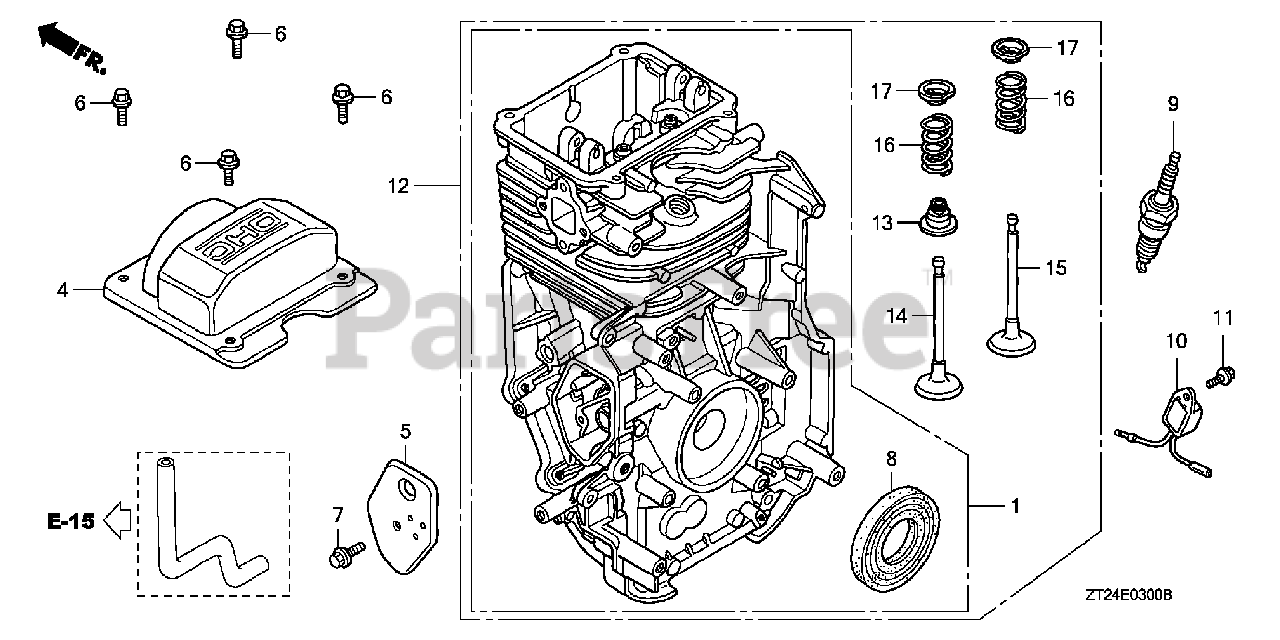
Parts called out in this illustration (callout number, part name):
4	COVER, CYLINDER HEAD
4	COVER, HEAD
5	COVER, BREATHER (BREATHER VALVE ASSY.)
6	BOLT, FLANGE (6X12) (CT200)
7	BOLT, FLANGE (6X14) (CT200)
8	OIL SEAL (25.4X62X6)
9	SPARK PLUG (BPR6ES) (NGK)
10	ALERT UNIT, OIL
11	BOLT, FLANGE (6X12) (CT200)
12	CYLINDER ASSY.
13	SEAL, VALVE STEM
14	VALVE, IN. (ROCKNEL)
15	VALVE, EX.
16	SPRING, VALVE
17	RETAINER, VALVE SPRING
